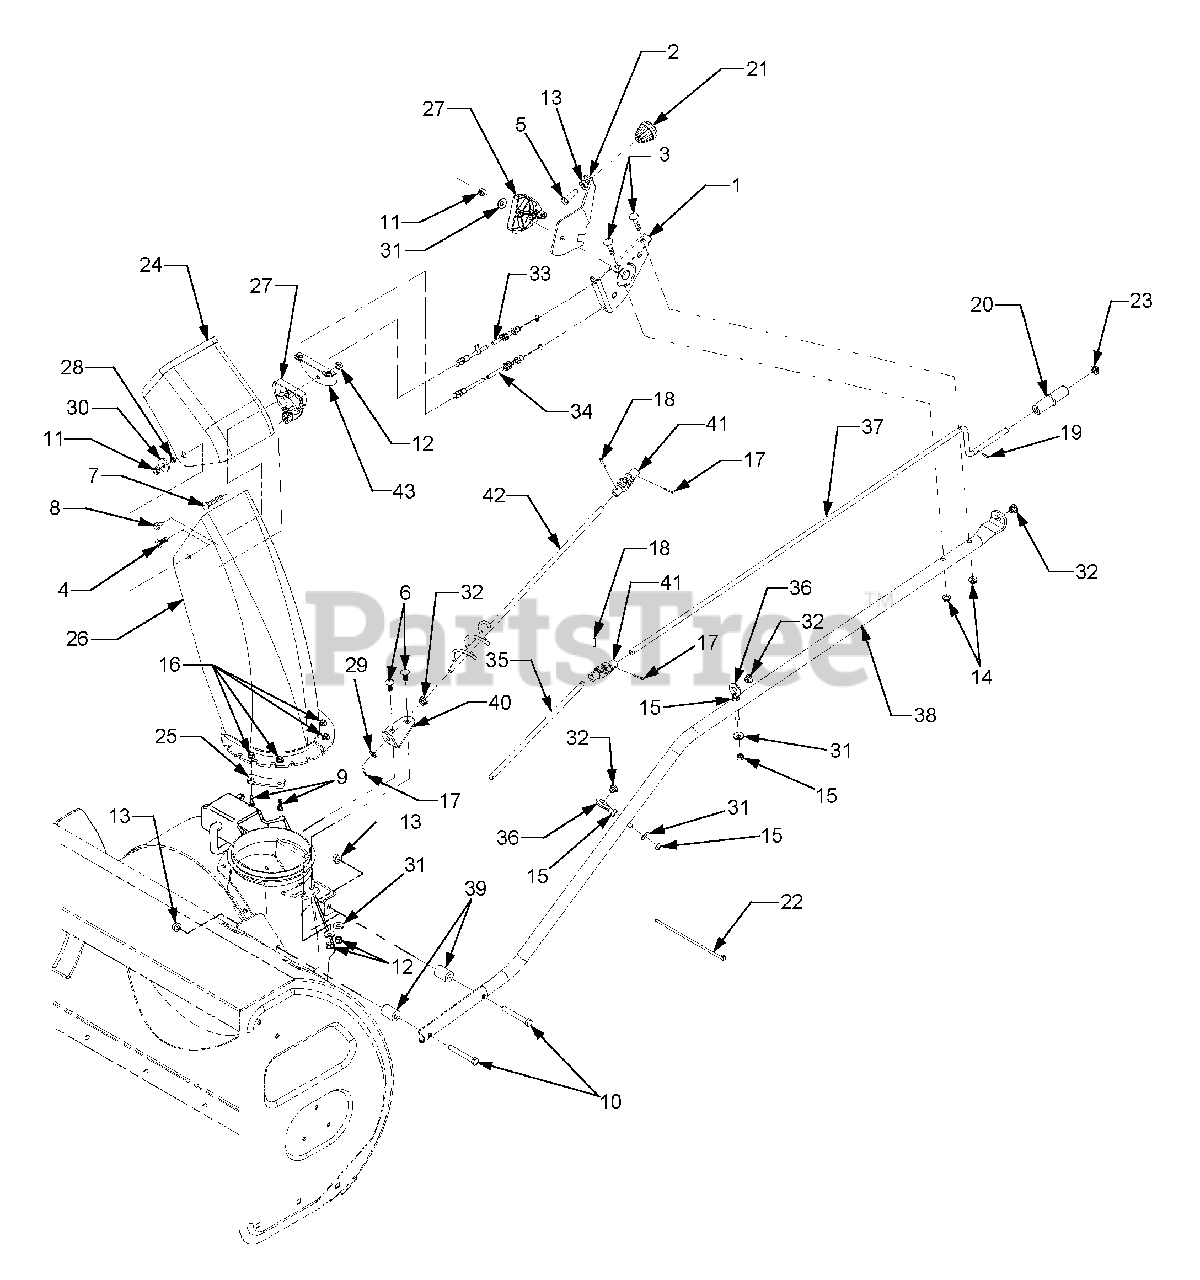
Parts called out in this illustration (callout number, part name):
1	Bracket Ass'y, Chute Tilt
2	Handle, Chute Tilt
3	Bolt, Carriage, 5/16-18 X 1.5
4	Bolt, Carriage, 5/16-18 X 1.0
5	Screw, Hex Cap, 3/8-16 x 1.25
6	Bolt, Carriage, 5/16-18 X .75
7	Bolt, Carriage, 5/16-18 X 1.75
8	Screw, Hex Wash. Hd. Tapp 1/4-14 X .625
9	Screw, Hex Cap, 1/4-20 X .75 GR5
10	Screw, Hex Cap, 3/8-16 x 2.75 GR5
11	Nut, Hex Center Lock, 5/16-18
12	Nut, Hex Insert Lock, 5/16-18
13	Nut, Hex Flange Lock, 3/8-16
14	Nut, Hex Flange Lock, 5/16-18 GR5
15	Nut, Hex, 5/16-18
16	Nut, Hex Flange Lock, 1/4-20
17	Pin, Cotter, 3/32 X .75
18	Pin, Spirol, 1/8 X .812
19	Pin, Roll, 1/8 X .63
20	Knob, Crank
21	Knob, Shift
22	Tie, Cable
23	Cap, Push
24	Chute, Upper Discharge
25	Keeper, Chute Flange
26	Chute, Lower Discharge
27	Guide, Chute Tilt Cable
28	Spacer, Chute Pivot
29	Washer, Flat, .385 X .62 X .06
30	Washer, Flat, .344 X 1.125 X .12
31	Washer, Bell, .345 X .88 X .06
32	Bushing, Plastic
33	Cable, Chute Tilt w/Clip
34	Cable, Chute Tilt
35	Rod, Chute Crank
37	Rod, Chute Crank
38	Tube, Chute Crank Support
39	Spacer, .375 ID x 1.0 OD x 1.25 Lg
41	Block Ass'y, Joint
42	Crank Ass'y, Chute
43	Bracket, Cable
